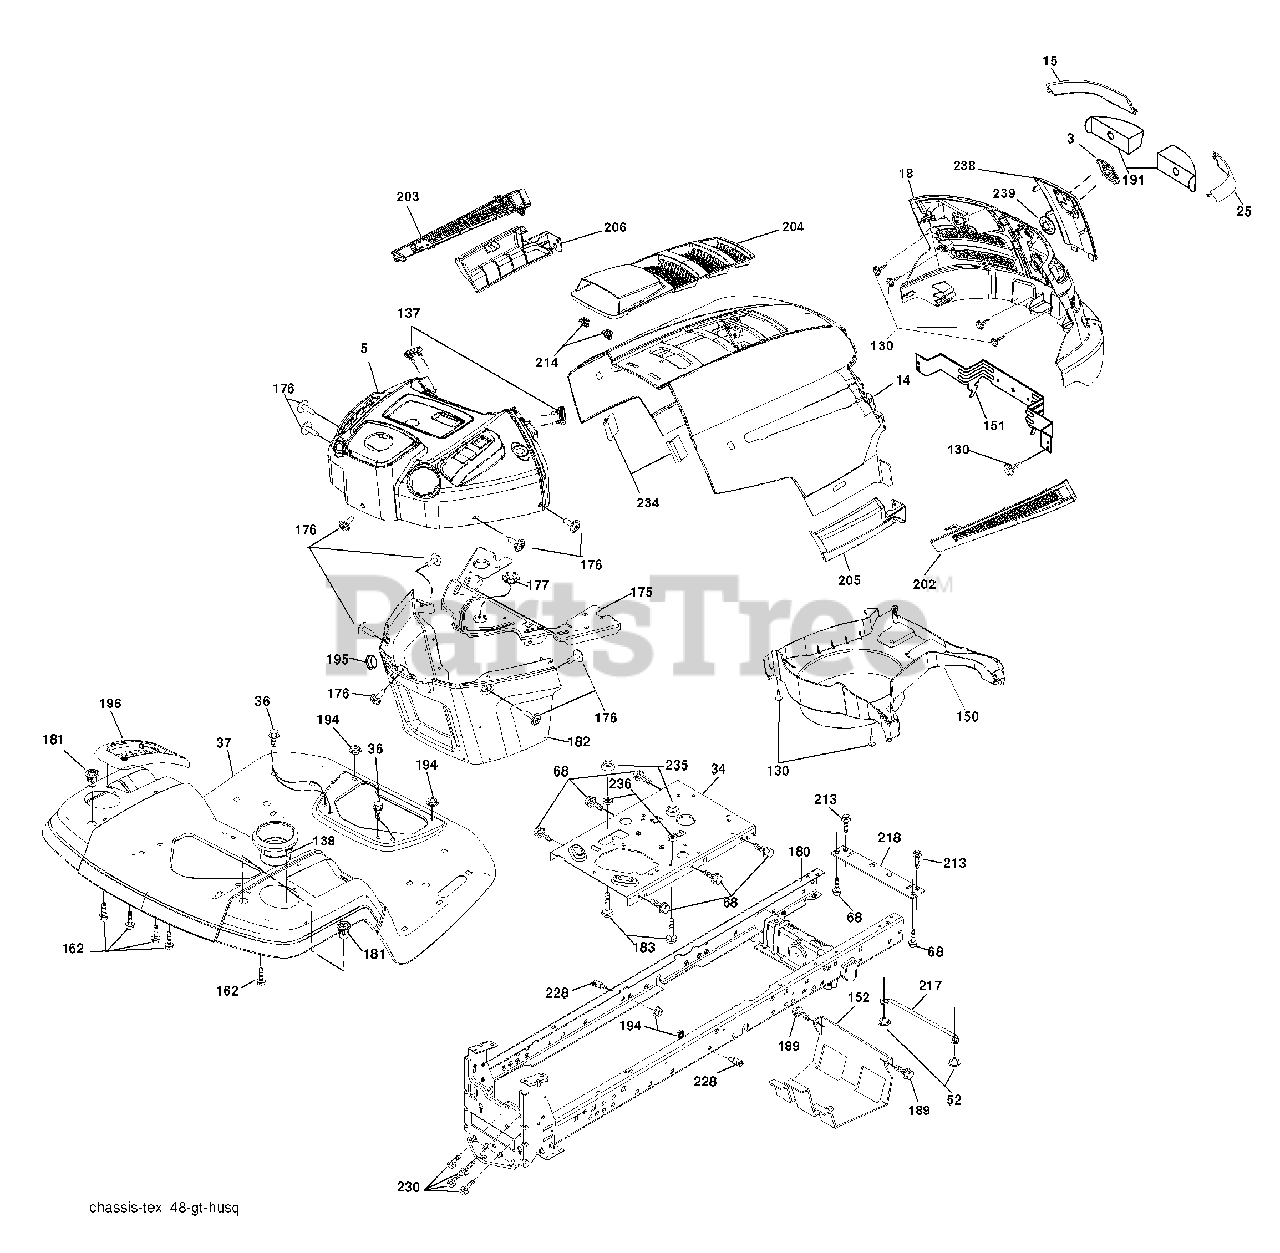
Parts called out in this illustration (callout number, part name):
3	Logo
5	Dash
14	Hood
15	Lens LH
18	Grille/Lens Asm.
25	Lens RH
34	Plate Engine
36	Screw 5/16-18 x 3/4
37	Fender
52	Nut Crown Lock 5/16
68	Screw THDROL 5/16-18 x 1/2
130	Screw
137	Bumper Dash
138	Cupholder
151	Bracket Pivot
152	Shield Browning
175	Crossmember
176	Screw 10-24 x 5/8
177	Bushing Steering
180	Chassis
181	Bushing Mtg. Fender Crgo
182	Dash Lower
183	Bolt 5/16-18 unc x 1-1/4
189	Screw 5/16-18 x 3/4
191	Insert Reflective
194	Nut Lock Hex Flange 5/16-18
195	Plug Dash
196	Console Asm. Deck Lift
202	Vent Side Hood RH
203	Vent Side Hood LH
204	Vent Top Hood
205	Skirt Side RH
206	Skirt Side LH
213	Bolt 5/16-18 x 3/4
214	Clip Retainer
217	Rod Pivot Hood
218	X-Piece Hood Stop
228	Stud Fastener
230	Bolt Shoulder 5/16-18
234	Bumper Hood
235	Spacer Fender
236	Nut Lock 5/16-18 unc
238	Trim
239	Clip Tinnerman
